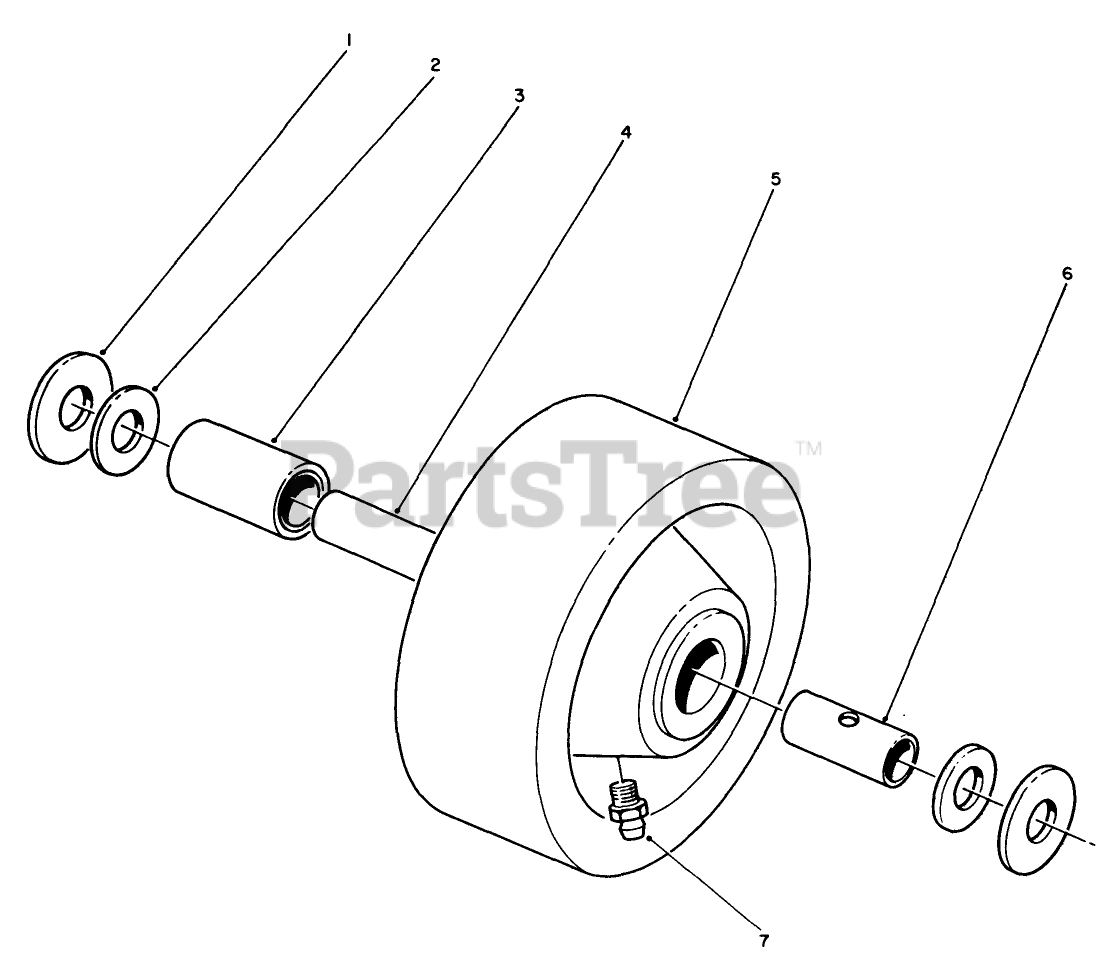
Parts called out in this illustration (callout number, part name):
1	THRUST WASHER
2	BEARING RETAINER
3	ROLLER BEARING
4	SPANNER-TIRE
5	WHEEL
6	SPANNER BUSHING
7	FITTING-GREASE
